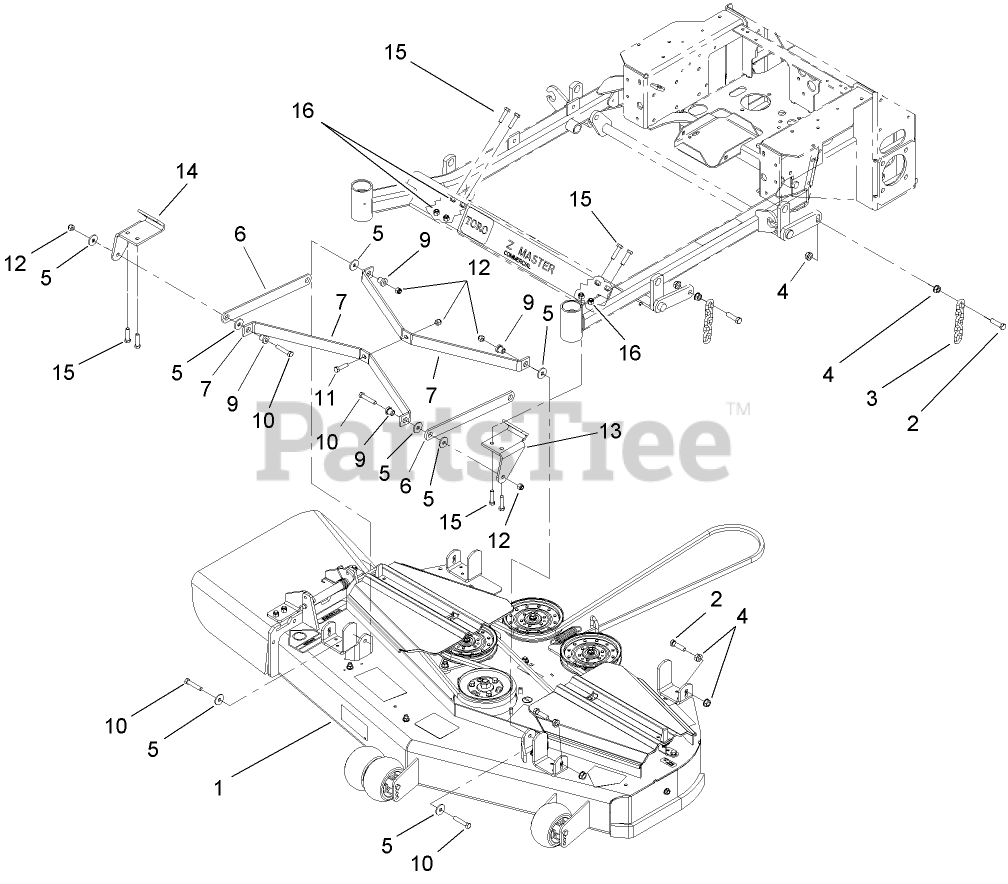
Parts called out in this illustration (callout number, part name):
1	DECK ASM
2	SCREW-HH
3	CHAIN-LIFT, DECK
4	NUT-HF
5	WASHER
6	STRUT-FLAT
7	BRACE-CROSS
9	BUSHING-PULLEY
10	SCREW-HH
11	SCREW-HH
12	NUT-LOCK, NI
13	PLATE-PULL, LH
14	PLATE-PULL, RH
15	SCREW-HH
16	NUT-HHF, WHIZ
